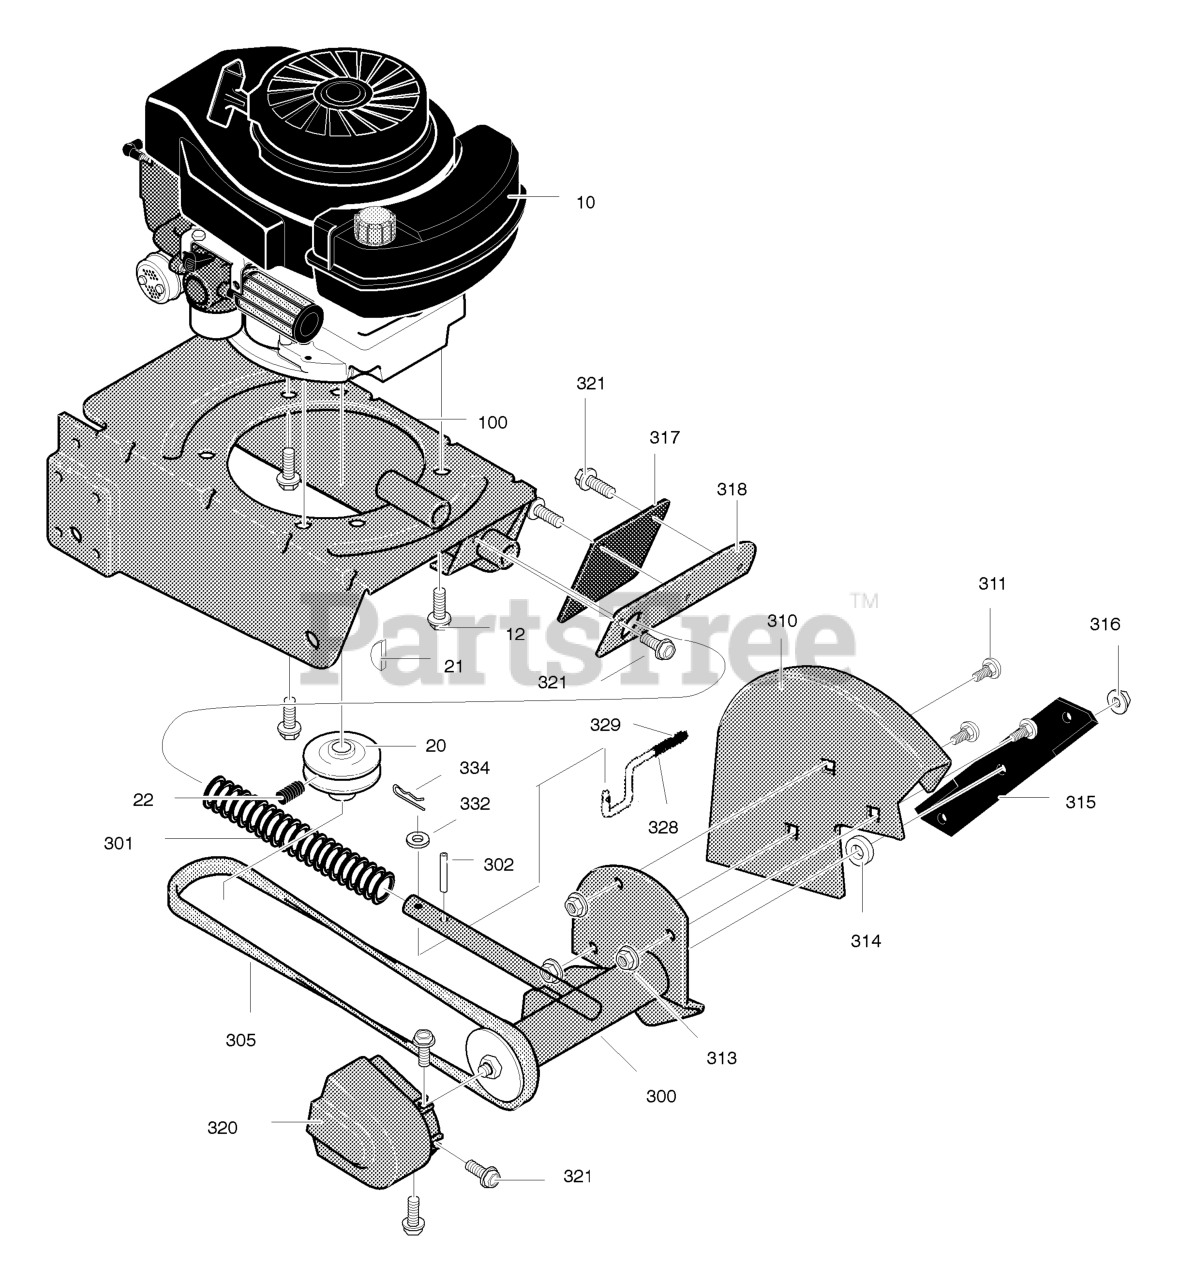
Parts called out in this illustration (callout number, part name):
10	Engine
20	Pulley, V3L
21	Key, Hi Pro #505
22	Screw, Set
100	Frame, Edger
300	Quill Assembly
302	Spring Pin
305	Belt, V4L
310	Blade Guard
311	Bolt, Carriage
313	Nut, 5/16-18
314	Flat washer
315	Blade, Edger
316	Nut, 1/2-20
317	Deflector, Rubber
318	Plate, Rubber Flap
320	Belt Guard
321	Screw, 10-16x.50
328	Lever, Blade
329	Grip, Blade Lever
332	Washer
334	Pin, Hair
